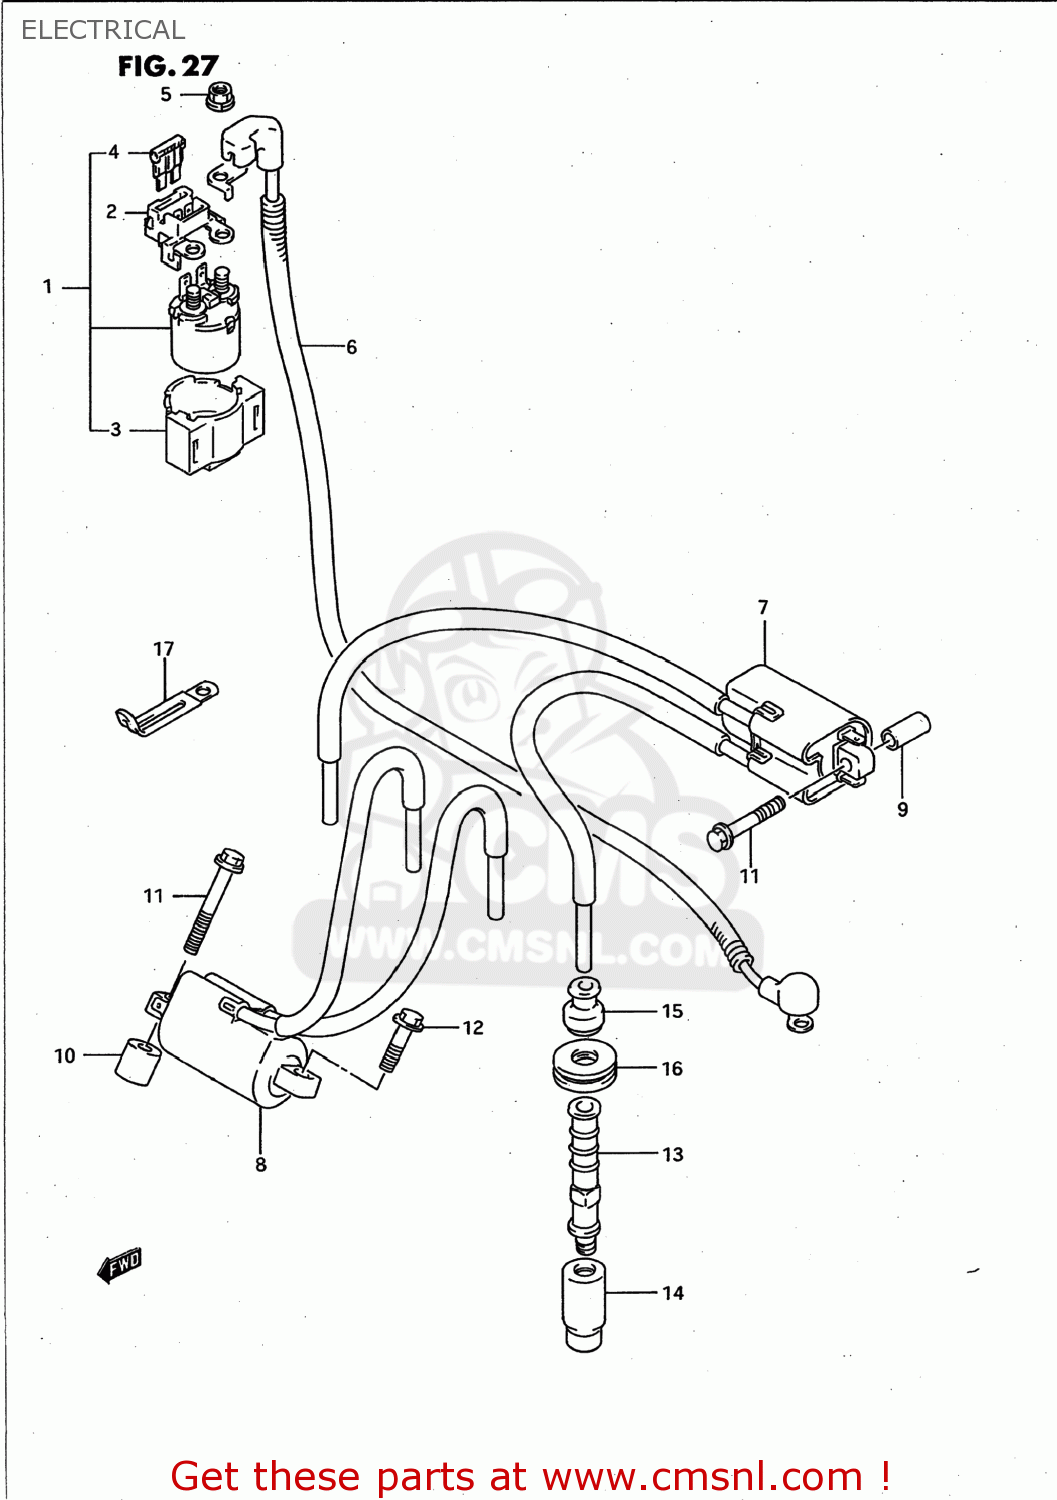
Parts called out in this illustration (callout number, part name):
1	RELAY ASSY,STARTING MOTOR
2	TERMINAL,RELAY
3	BRACKET,STARTING MOTOR RELAY
4	FUSE (30A)
5	NUT
6	WIRE,STARTER MOTOR
7	COIL ASSY,IGNITION
8	COIL ASSY,IGNITION
9	SPACER
10	SPACER,IGNITION COIL 1
11	BOLT
12	BOLT
13	CAP,SPARK PLUG
14	SEAL,SPARK PLUG
15	SEAL,HIGH TENSION CORD
16	COVER,SPARK PLUG CAP
17	CLAMP
